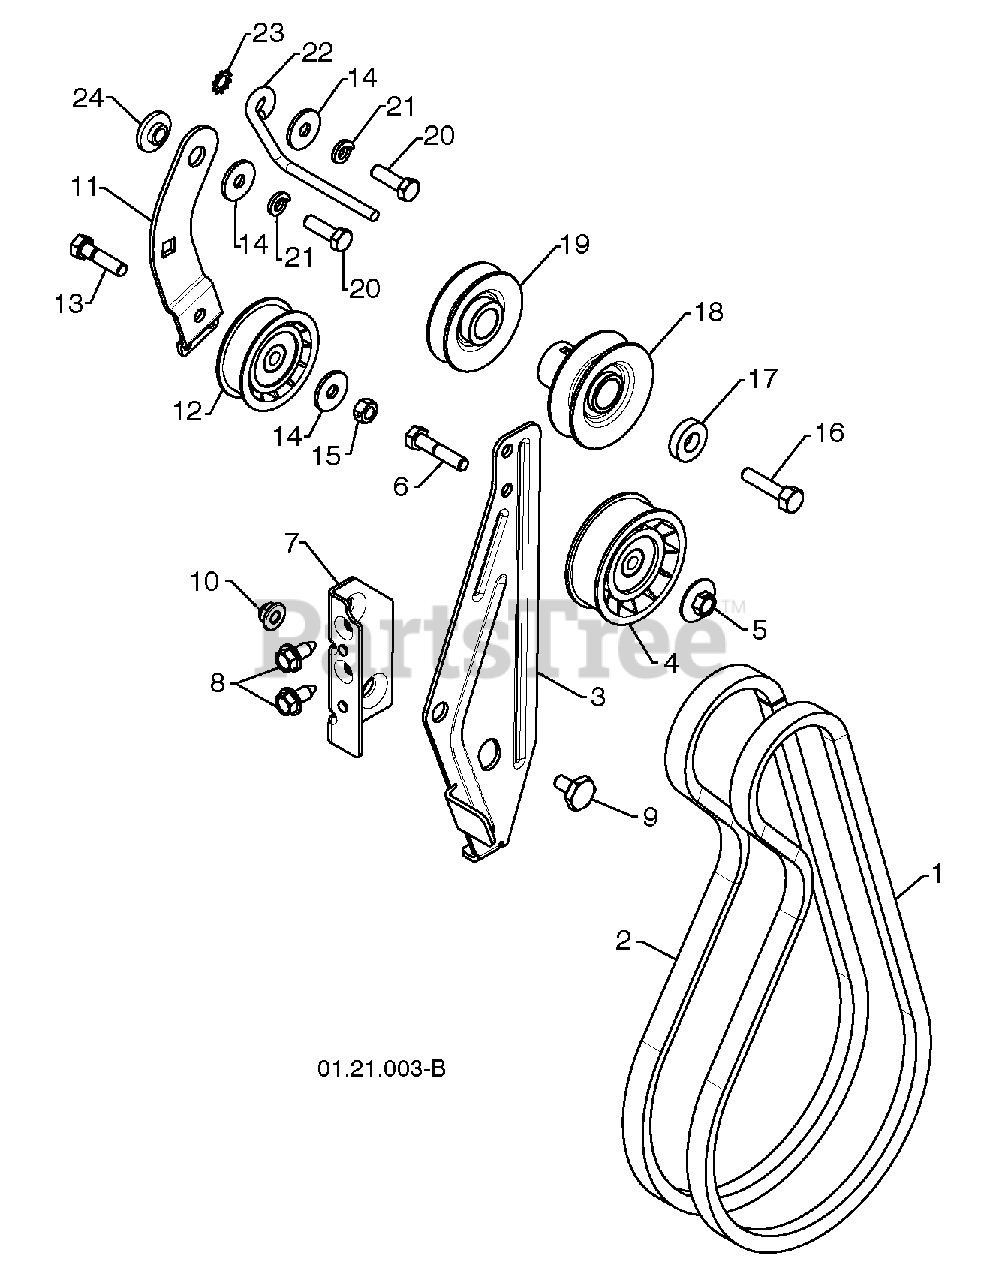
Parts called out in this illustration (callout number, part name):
1	IMPELLER BELT
2	TRACTION BELT
3	IDLER ARM BRACKET
4	IDLER PULLEY
5	NUT 5/16-18
6	SCREW 5/16-18 X 1 .50
7	IDLER BRACKET
8	SCREW 5/16-18 X .625
9	SHOULDER BOLT 5/16-18 X .500
10	NUT 5/16-18 NYLOCK
11	TRACTION IDLER ARM
12	TRACTION PULLEY
13	SCREW 5/16-18 X 1 .00
14	WASHER
15	NUT 5/16-18
16	SCREW 3/8-24 X 1.375
17	WASHER
18	PULLEY ENG IMPELLER
19	PULLEY ENG TRACTION
20	SCREW 5/16-18 X 1 .00
21	LOCKWASHER 5/16
22	BELT GUIDE
23	LOCKWASHER 5/16
24	IDLER BUSHING
